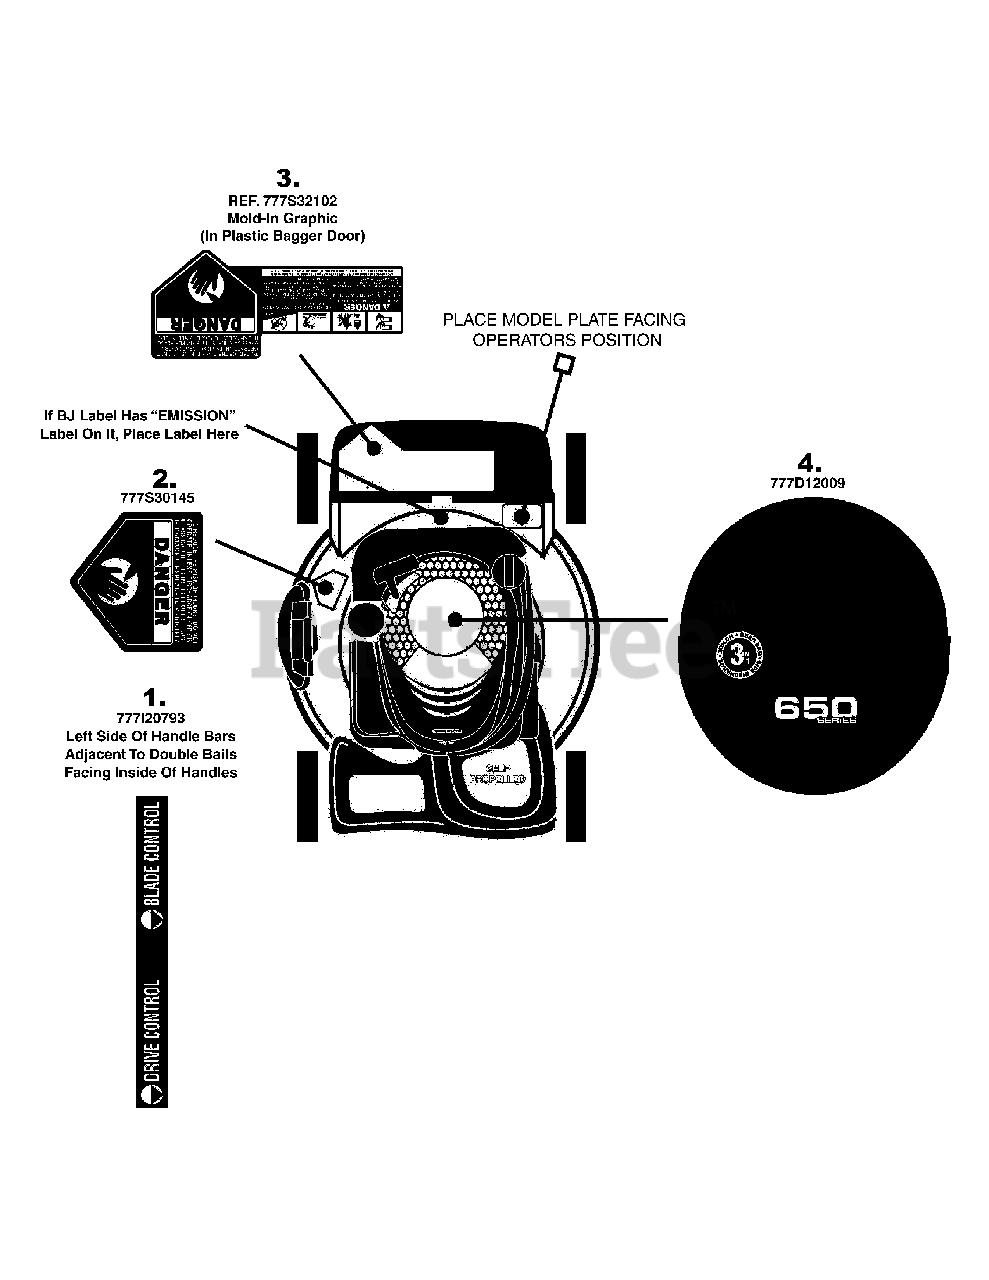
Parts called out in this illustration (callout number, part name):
1	LABEL-HANDLE
2	LABEL
3	LABEL
4	LABEL-MOWER SHROUD MTD GOLD 21"
